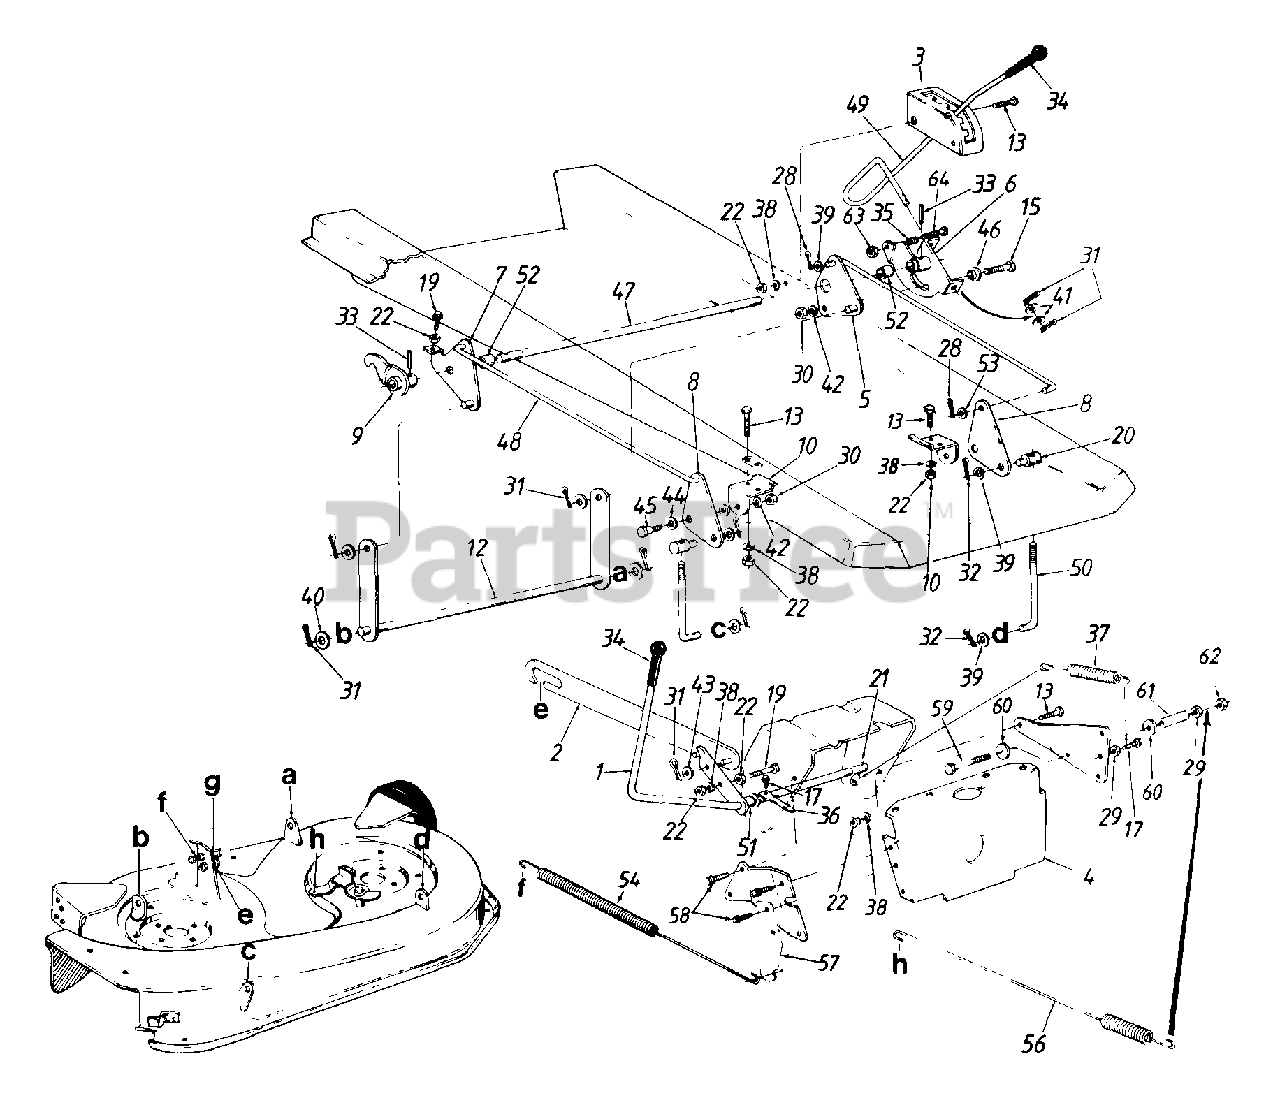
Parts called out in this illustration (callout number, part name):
1	Blade Engagement Lever Ass'y.
6	Deck Lift Handle Retainer Ass'y.
7	Deck Lift Brkt. Ass'y.
8	Deck Lift Bracket
9	Deck Lift Float Brkt Ass'y.
10	Deck Lift Pivot Brkt.
12	Stabilizer Shaft Ass'y.
13	Hex Bolt 5/16-18 x .75" Lg.
15	Hex Bolt 3/8-16 x 1" Lg.
17	Hex TT-Tap Scr. #12-24 x .5" Lg.
19	Hex Wash.-Tap Scr. 5/16-18 x 1.25" Lg.
20	Ferrule
21	Clevis Pin
22	Hex Nut 5/16-18 Thd.
28	Cotter Pin 3/32" Dia.
29	Hex Nut 1/4-20 Thd.
30	Hex Nut 3/8-16 Thd.
31	Internal Cot. Pin 1/2" Dia.
32	Int. Cot. Pins 3/8" Dia.
33	Spring Pin Spir. 1/4" Dia.
35	Compression Spring .9" Lg.
36	Switch Actuator
37	Ext. Spring 5.86" Lg.
38	L-Wash 5/16" I.D
39	Fl-Wash .385 I.D. x .62
40	Fl-Wash .635 I.D. x 1.12
41	Fl-Wash .531 I.D. x .930
42	L-Wash 3/8" I.D.
43	Fl-Wash .385 I.D. x .87 O.D.
44	Spring Washer .530 I.D.
45	Shld Bolt .500" Dia x .215"
46	Shld Spacer .625" I.D.
47	Rear Hgt Adj. Shaft
50	J-Bolt 5.4" Lg
51	Spacer .511 I.D.
52	Spacer .885 I.D.
53	Fl-Wash 5/16" I.D.
54	Ext. Spring 22.05" Lg.
56	Ext. Spring - 15-5/8" (32" Deck)
57	Spring Anchor
58	Hex Wash Hd. AB-Tap Scr. 1/4 x .62" Lg.
59	Hex Bolt 1/4-20 x 2.5" Lg.
60	Fl-Wash .25" I.D. x .93" O.D.
61	Spacer .255" I.D.
62	Hex L-Nut 1/4-20 Thd.
63	Hex L-Nut 1/4-20 Thd.
64	Hex Bolt 1/4-20 x 1.25" Lg.
